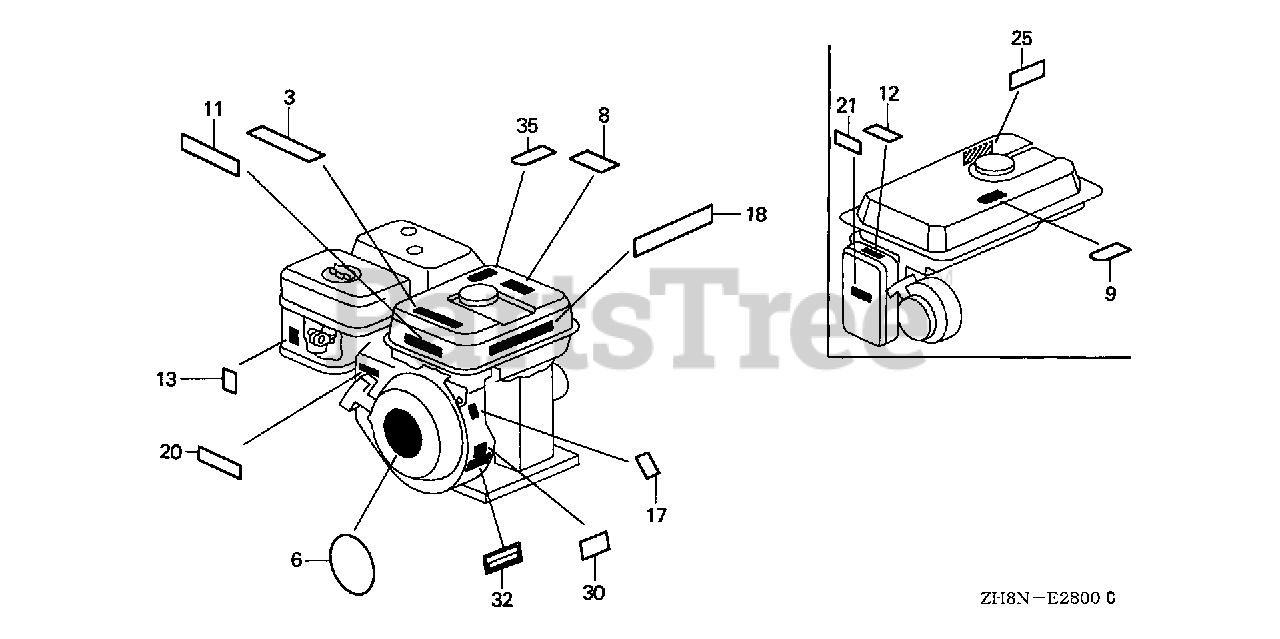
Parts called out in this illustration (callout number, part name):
3	LABEL, CAUTION
6	EMBLEM (5.5)
8	MARK, CAUTION
13	MARK, CHOKE
20	MARK, THROTTLE INDICATION
